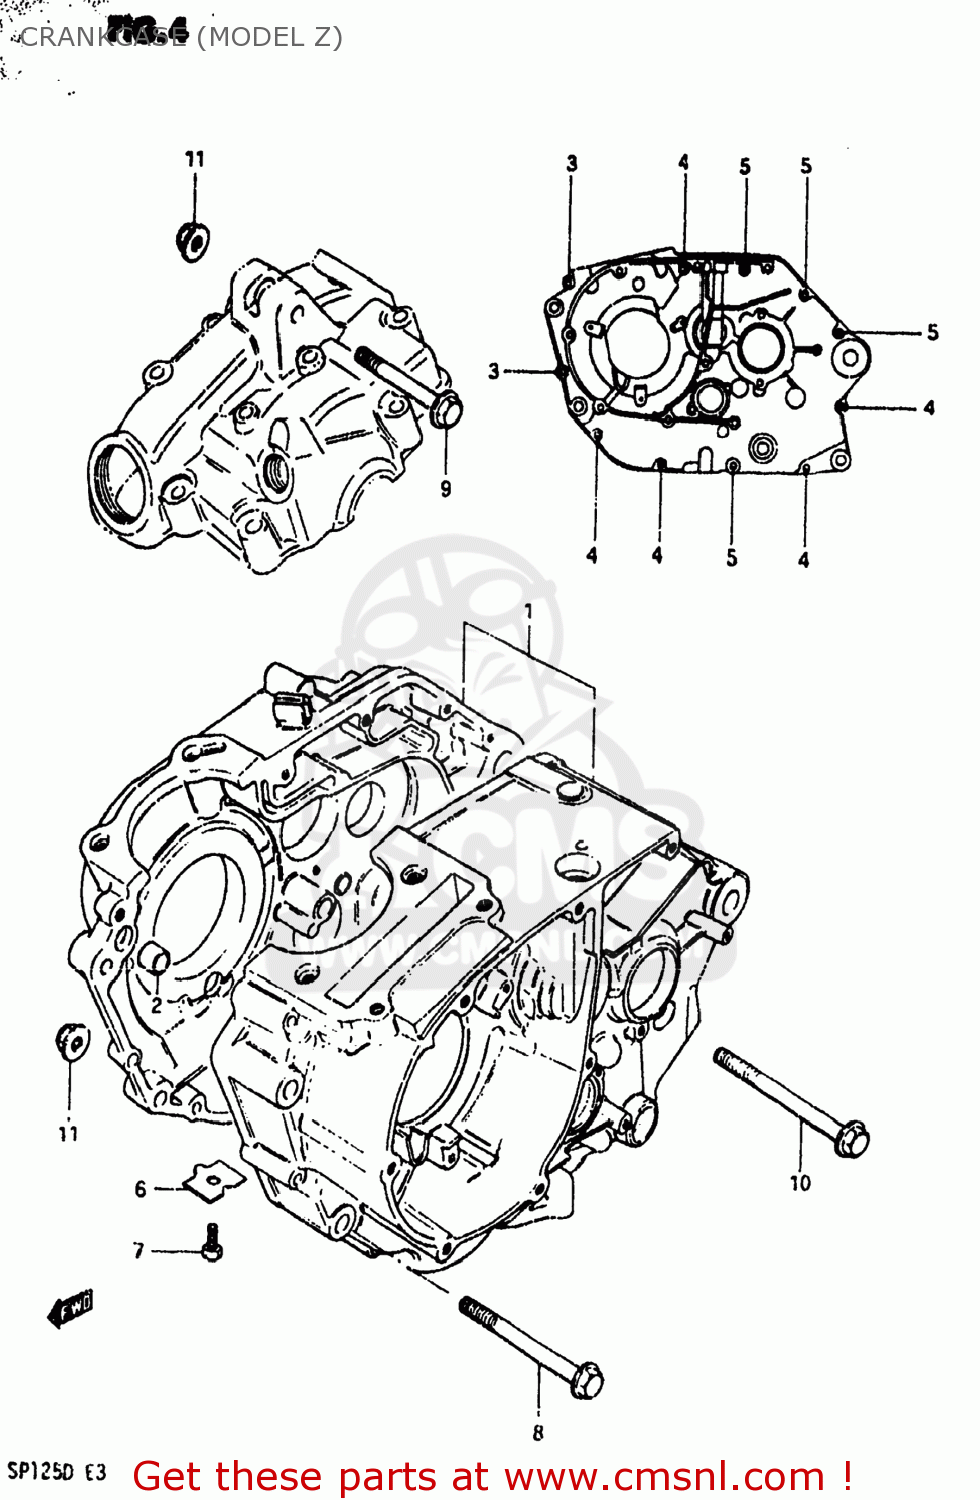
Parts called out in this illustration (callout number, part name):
1	CRANKCASE SET
2	PIN
3	BOLT
4	BOLT
5	BOLT
6	PLATE,OIL GALLERY PLUG
7	BOLT
8	BOLT(8X80)
9	BOLT
10	BOLT
11	NUT
